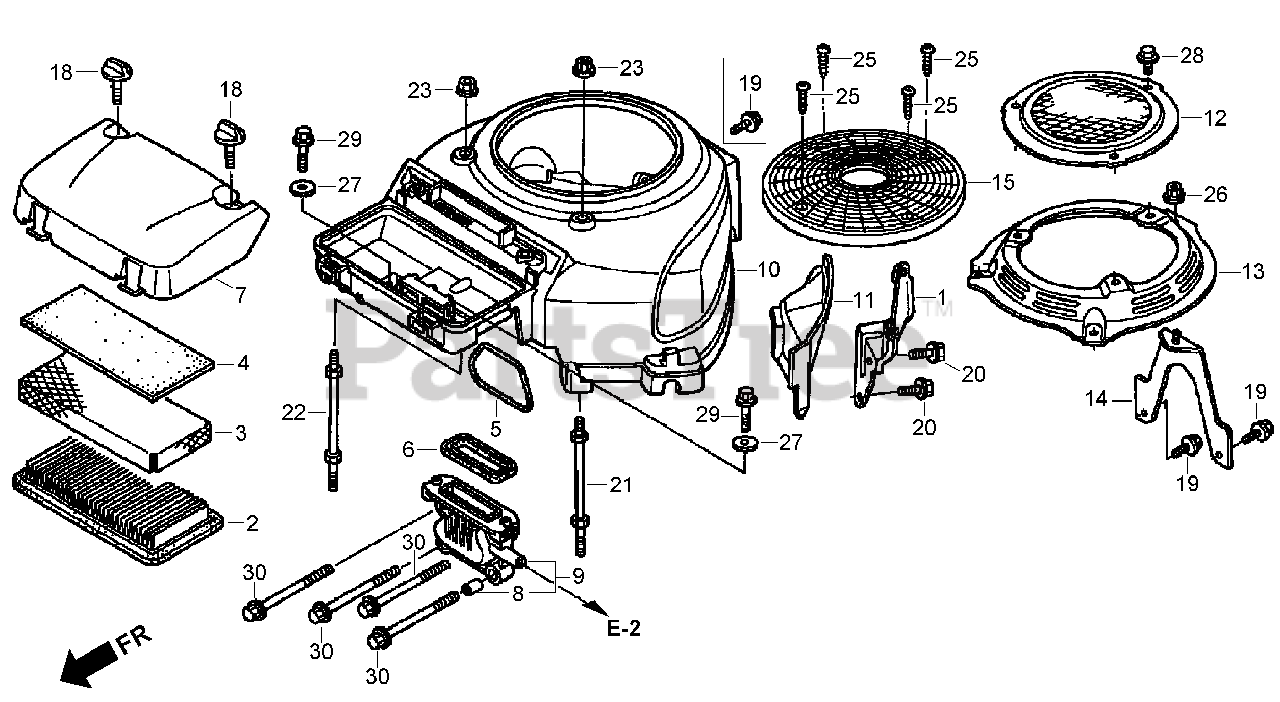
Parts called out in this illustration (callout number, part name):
1	STAY-PUMP, FUEL
2	ELEMENT-CLEANER, AIR
3	GRID-CLEANER, AIR
4	FILTER (OUTER)
5	GASKET-CLEANER, AIR
6	SEAL-HOUSING, AIR CLEANER
7	COVER-CLEANER, AIR
8	COLLAR A-CLEANER, AIR
9	ELBOW-CLEANER, AIR
10	COVER-FAN (NH1) (BLACK)
11	PLATE-SIDE
12	PROTECTOR-COVER, FAN (NH105) (MATTE BLACK)
13	SPACER-MOUNTING, RECOIL STARTER (NH105) (MAT BLACK)
14	BRACKET-MOUNT, RECOIL
15	GRID-SCREEN NH105 (MATTE BLACK)
18	BOLT-AIR CLEANER (6MM)
19	BOLT-FLANGE (6X14) (CT200)
20	BOLT-FLANGE (6X14) (C T200)
21	BOLT-STUD, LEFT (IGNITION COIL)
22	BOLT-STUD, RIGHT (IGNITION COIL)
23	NUT-FLANGE (6MM)
25	SCREW-TAPPING (4X30) (P0)
26	NUT-FLANGE (6MM)
27	WASHER-PLAIN (6MM)
28	BOLT-FLANGE (6X8)
29	BOLT-FLANGE (6X12)
30	BOLT-FLANGE (6X100)
